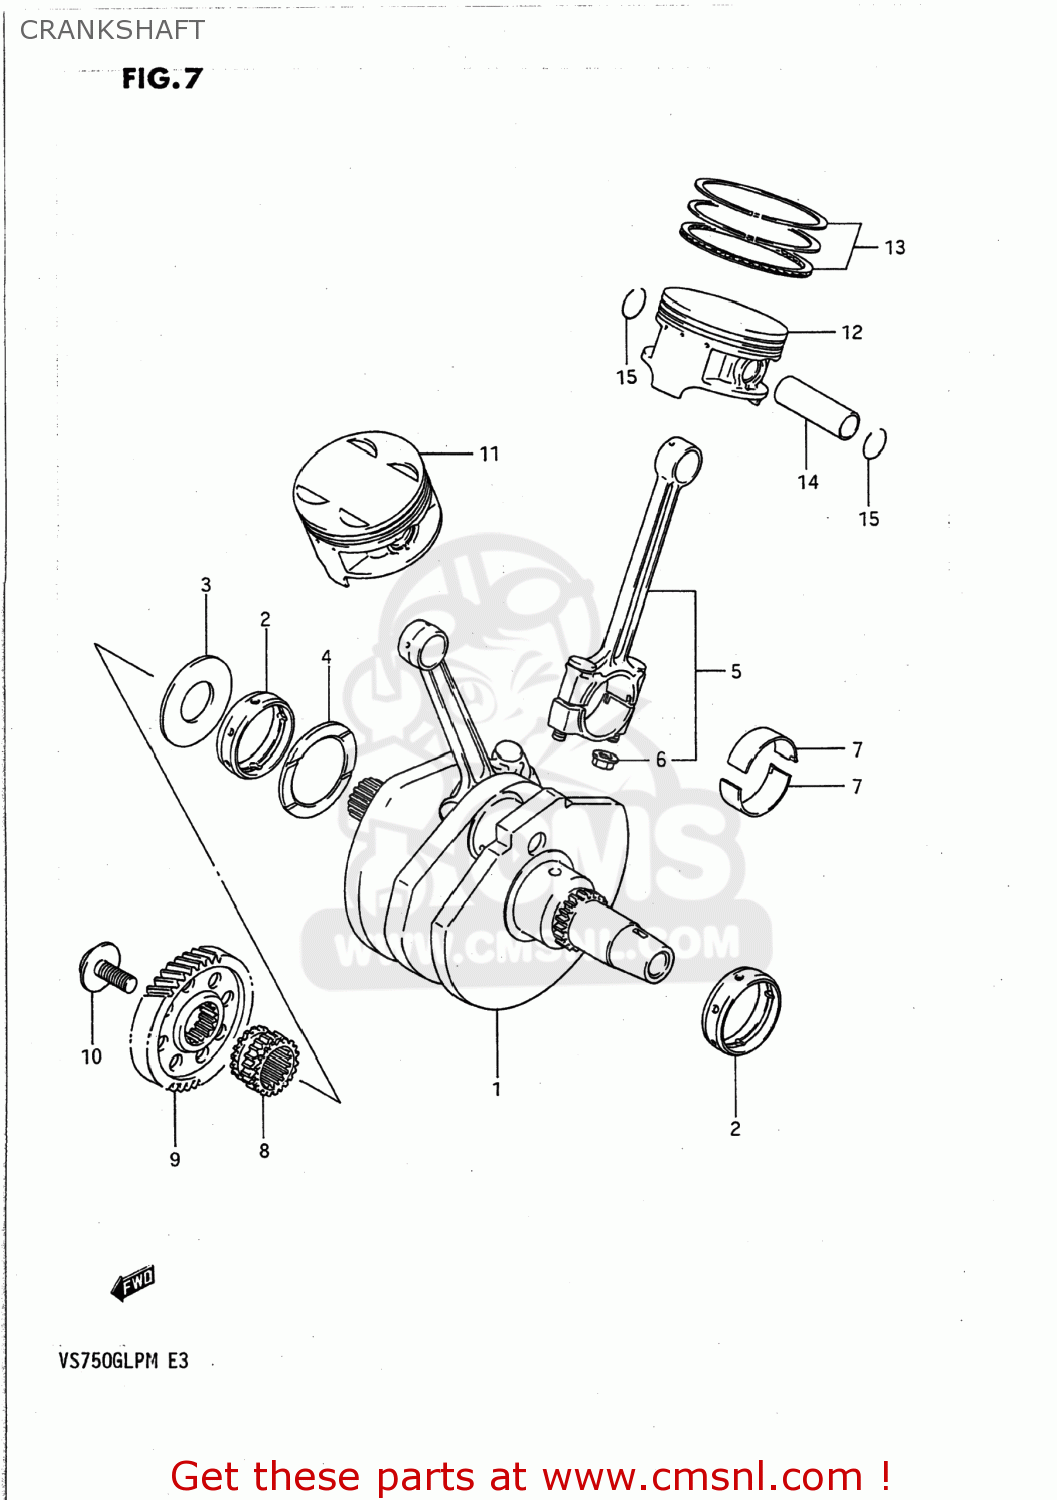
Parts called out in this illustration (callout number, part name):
1	CRANKSHAFT
2	METAL,CRANKSHAFT
3	WASHER,CRANK THRUST
4	WASHER(48.1X64X1.94)
5	CONNECTING ROD ASSEMBLY
6	NUT
7	BEARING,CRANK PIN
8	SPROCKET,CAM CHAIN DRIVE,R
9	GEAR,PRIMARY DRIVE
10	BOLT(12X28)
11	PISTON
12	PISTON
13	RING SET,PISTON
14	PIN,PISTON
15	CIRCLIP,PISTON PIN
